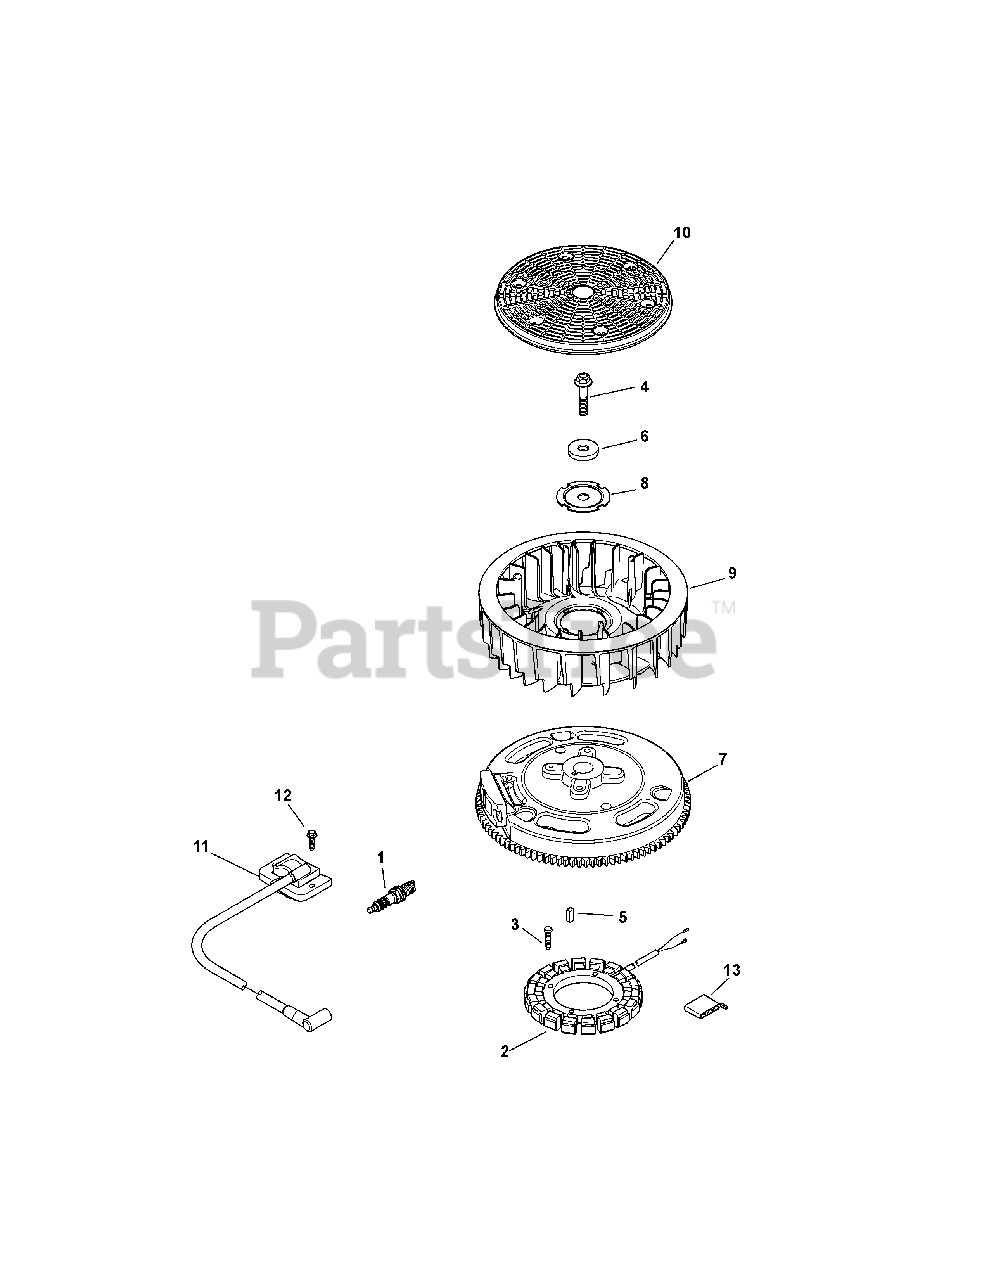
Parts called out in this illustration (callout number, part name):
1	Spark Plug
2	15 Amp Stator Kit
3	Screw, M5 x 0.8 x 25
4	Hex Flange Screw
7	Flywheel Assembly
8	Fan Mounting Plate
9	Fan
11	Module Ignition Kit
12	Screw, M5 x .8 x 20
